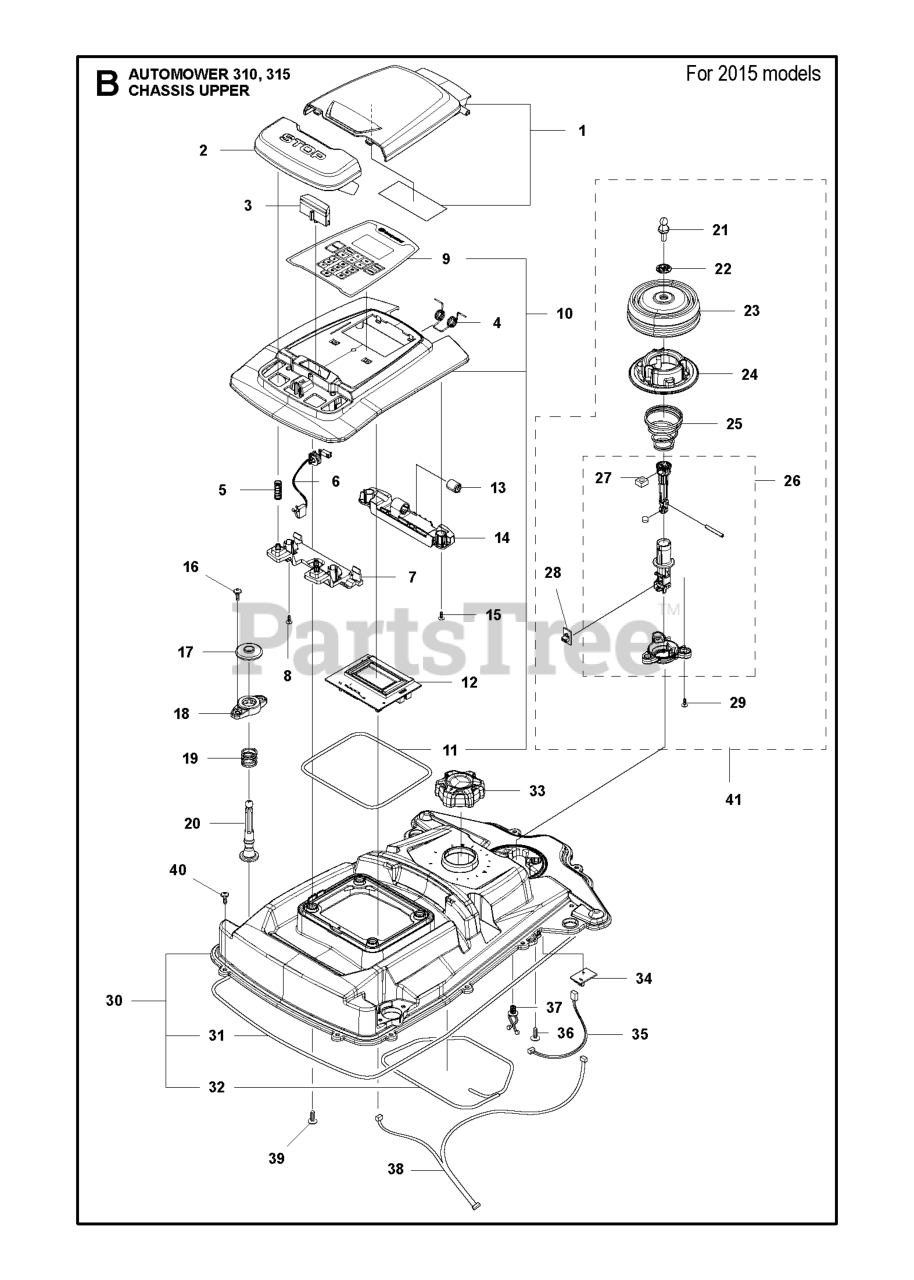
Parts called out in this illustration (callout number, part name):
2	BUTTON STOP
4	TORSION SPRING DT=1,3MM
5	SPRING LOCK STOP BUTTON
6	SWITCH STOP BUTTON NO ANCHOR
7	SUPPORT REAR
8	SCREW 14MM
9	KEYBOARD 2.1" DISPLAY
10	COVER KIT 2.1" DISPLAY
11	SEALING STRIP P15 UPPER
12	PRINTED CIRCUIT ASSY PCBA MMI
13	DAMPER TORSION FA 1100
14	SUPPORT FRONT
15	SCREW 14MM
16	SCREW ITXPANT
17	GASKET COLUMN
18	HOLDER COLUMN
19	SPRING 1.8X17.2X20
21	STUD SNAPLOC
22	WASHER JOYSTICK
23	BELLOWS LIFT-COLLISION
24	RETAINER COLLISION SPRING
25	SPRING COLLISION JOYSTICK
26	JOYSTICK KIT
28	PRINTED CIRCUIT ASSY PCBA LIFT
29	SCREW 14MM
30	CHASSIS KIT UPPER
31	SEALING STRIP P 15 CHASSI LOW
32	SEALING STRIP P15 UPPER
33	KNOB HEIGHT ADJUSTMENT
34	PRINTED CIRCUIT ASSY COLLISION
35	LOOM LIFT, COLLISION
36	SCREW ITXPANT
37	HOLDER TWIST LOCK
39	SCREW ITXPANT
40	SCREW ITXPANT
41	JOYSTICK KIT
